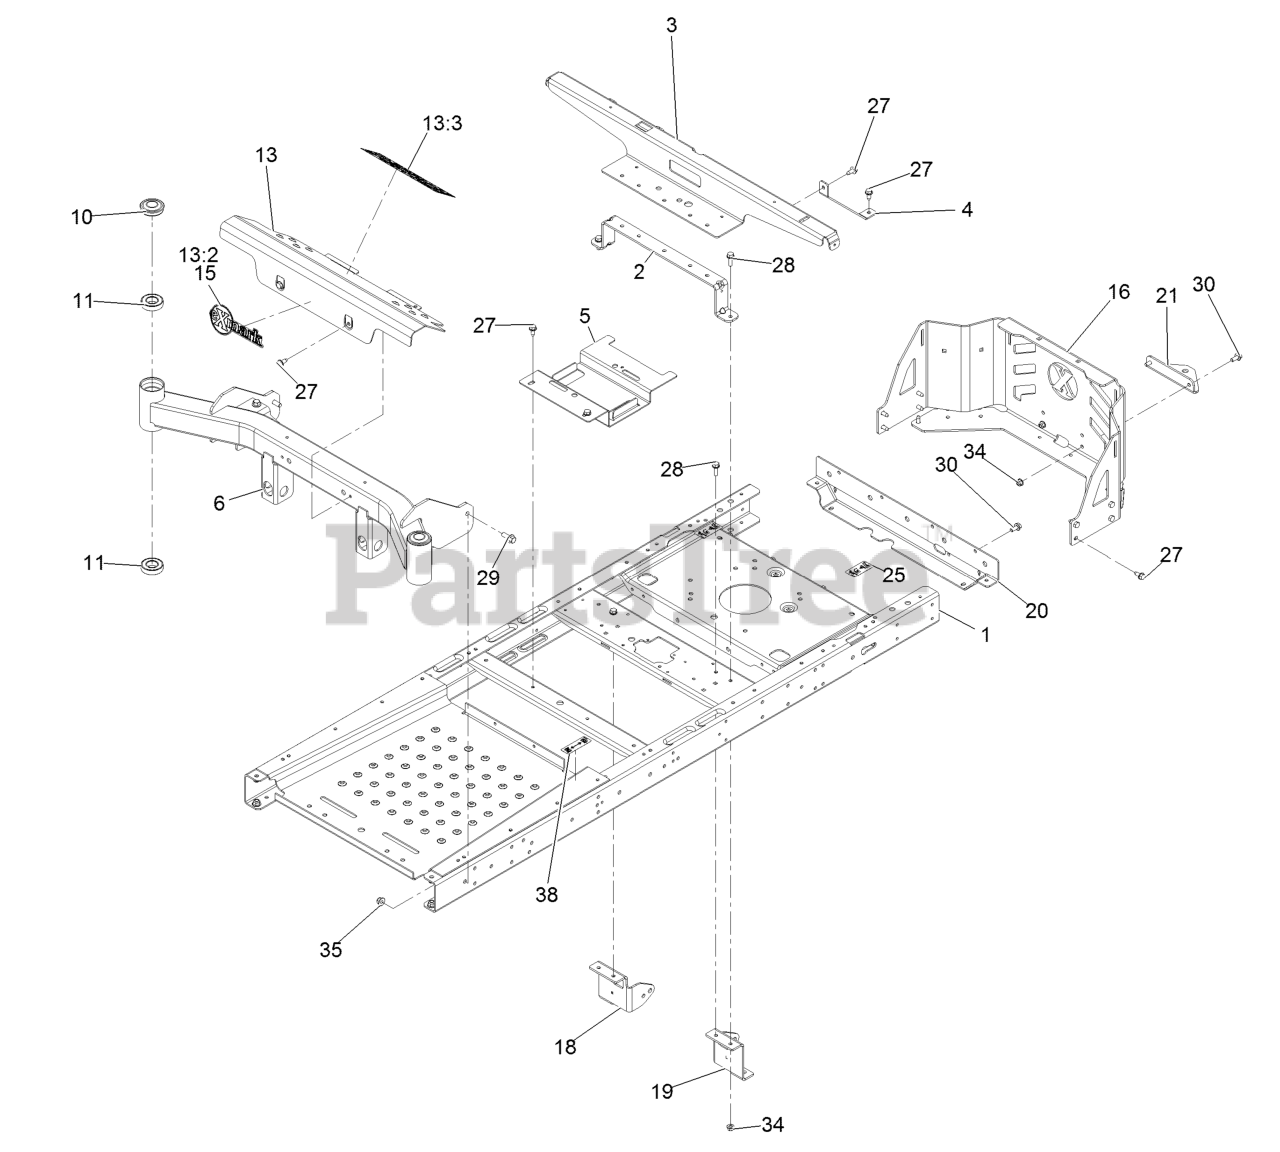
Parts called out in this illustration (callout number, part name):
1	RIVETED FRAME ASM (WIDE LEVER)
2	BRACE-SEAT, REAR (WIDE)
3	SUPPORT-POD
4	SUPPORT-TANK, REAR
5	BRACKET-BATTERY
6	FRONT AXLE ASM
10	CAP-GREASE
11	BEARING-BALL
13	FOOTREST
13:2	DECAL, EXMARK LOGO
13:3	DECAL-DANGER
15	DECAL, EXMARK LOGO
16	GUARD-ENGINE, WIDE
18	MOUNT-HYDRO, FRONT (RH)
19	MOUNT-HYDRO, FRONT (LH)
20	CROSSMEMBER-REAR, WIDE
21	BRACKET-HITCH
25	DECAL-BYPASS
27	Screw-HWH 5/16-18 X 3/4 Tf
28	SCREW-HHF
29	SCREW-HHF 3/8-16 X 1
30	SCREW-HHF
34	NUT-HF, NI
35	NUT-HF, NI
38	DECAL-BRAKE, PARKING
